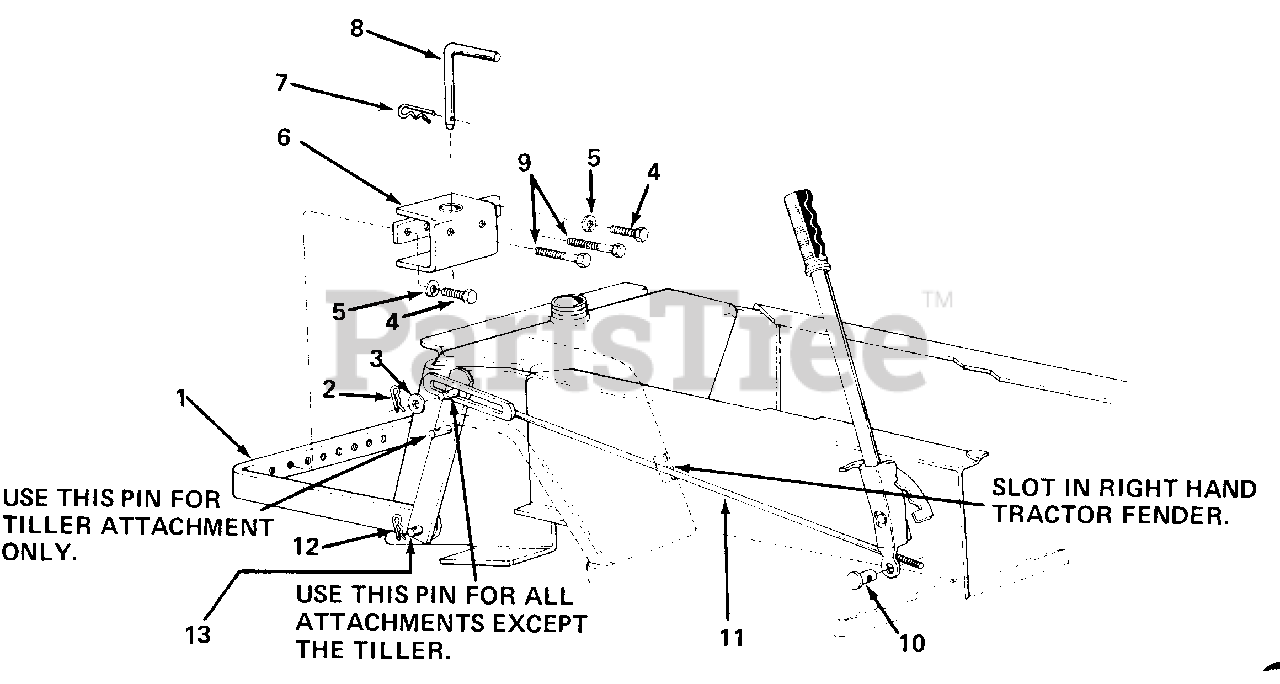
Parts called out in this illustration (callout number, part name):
3	Fl.-Wash. 1/2" I.D.
4	Hex Scr. 1/2-13 x 1.00" Lg.*
5	L.-Wash. 1/2" Scr.*
8	Hitch Pin
9	Hex Scr. 1/2-13 x 3.00" Lg.*
10	Adjustment Ferrule
13	Hitch Rod
